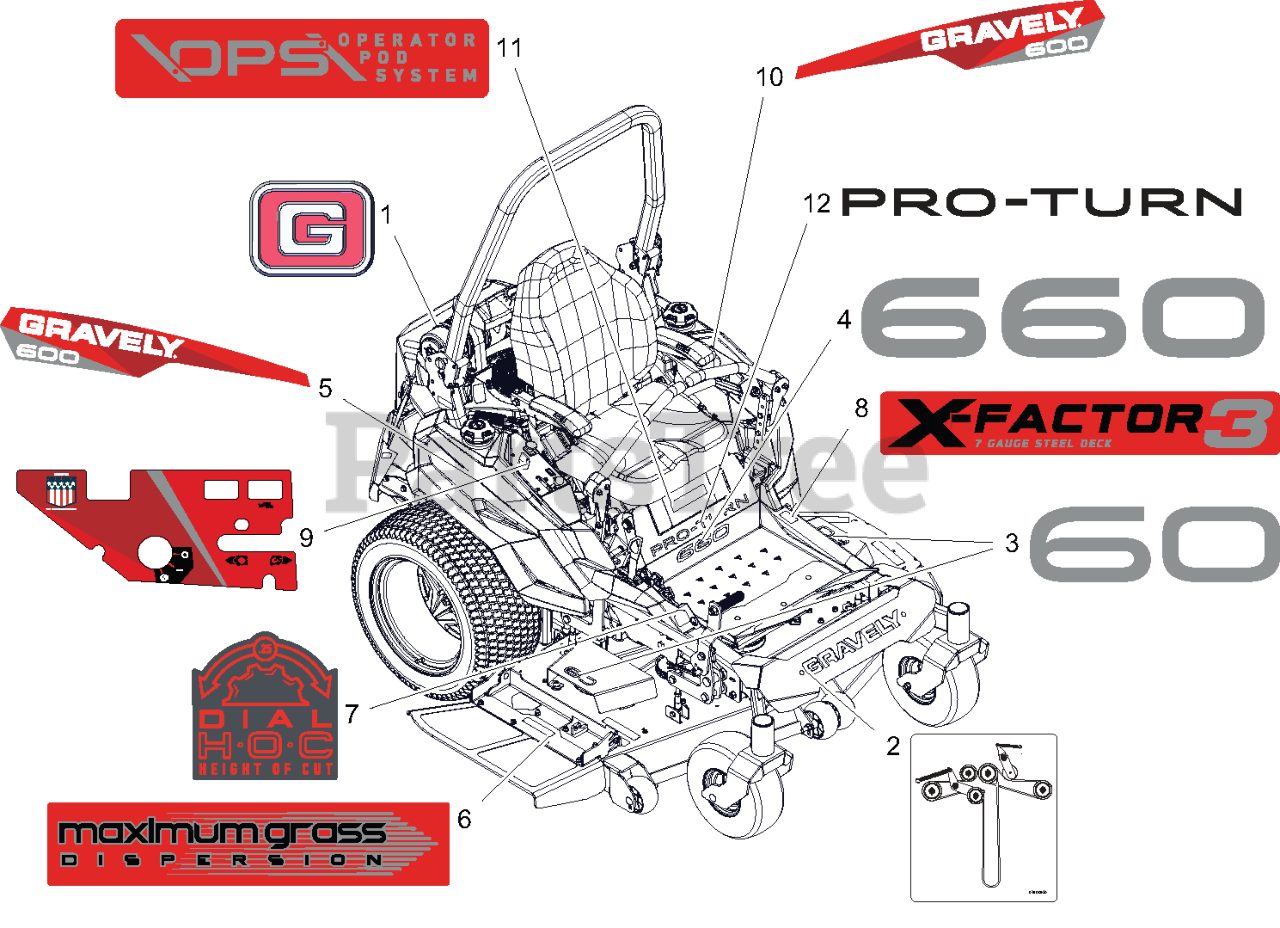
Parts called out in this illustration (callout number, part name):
1	DECAL, GRAVELY BRAND
2	DCL,BELT ROUTE-RH BK-SIDE IDLR
3	DECAL, DECK - 60
4	DECAL, PT660
5	DECAL, GRAVELY TANK - RH
6	DECAL, DECK - MAX GRASS
7	DECAL, COVER - HOC
8	DECAL, DECK - X-FACTOR 3
9	DECAL, CONTROL PANEL
10	DECAL, GRAVELY TANK - LH
11	DECAL, OPS
12	DECAL, PRO TURN
